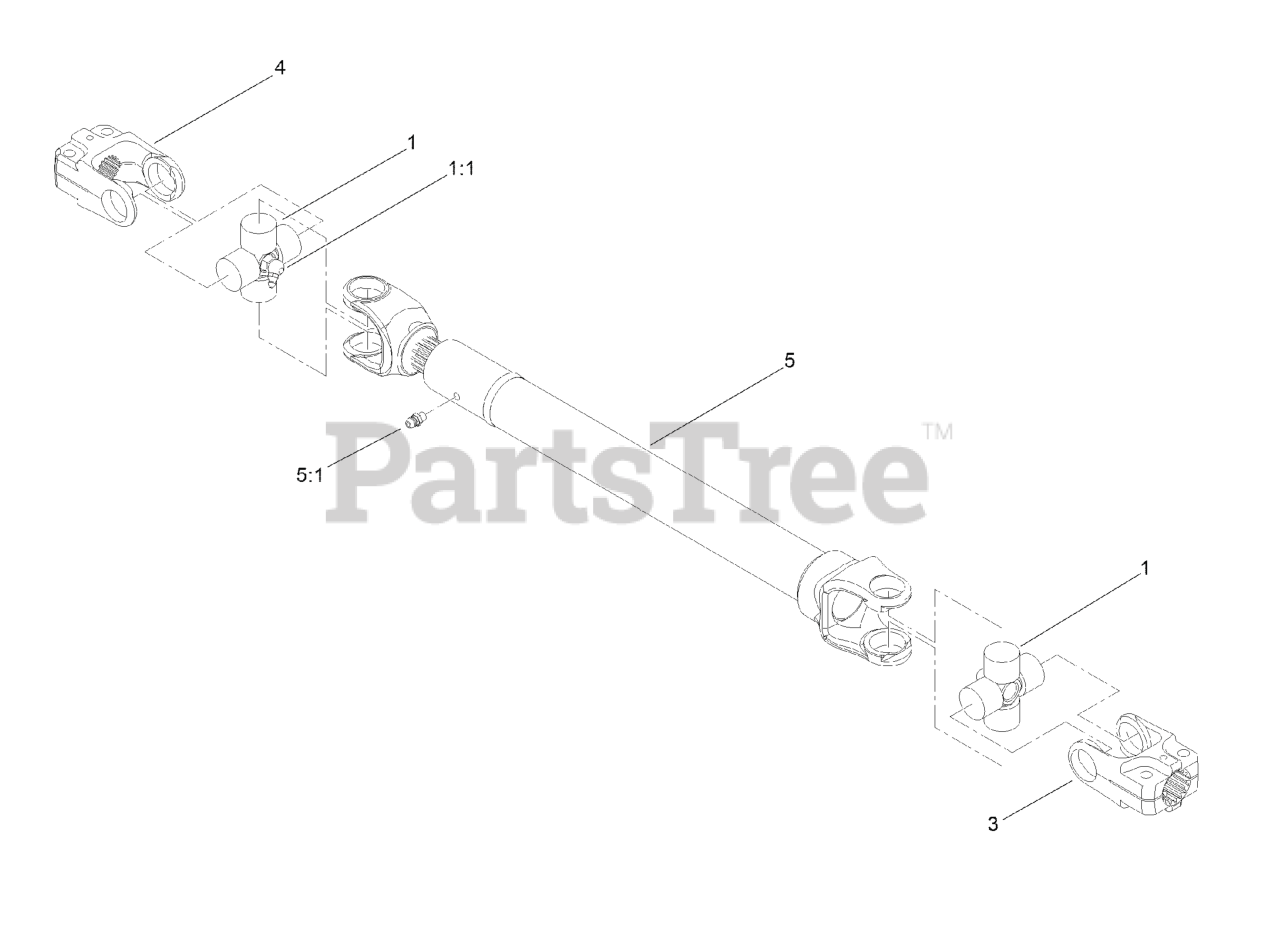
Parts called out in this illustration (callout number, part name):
1	CROSS AND BEARING KIT
1:1	FITTING-GREASE
3	YOKE-END
4	YOKE-END
5	Tube-Yoke, Slip
5:1	FITTING-GREASE
